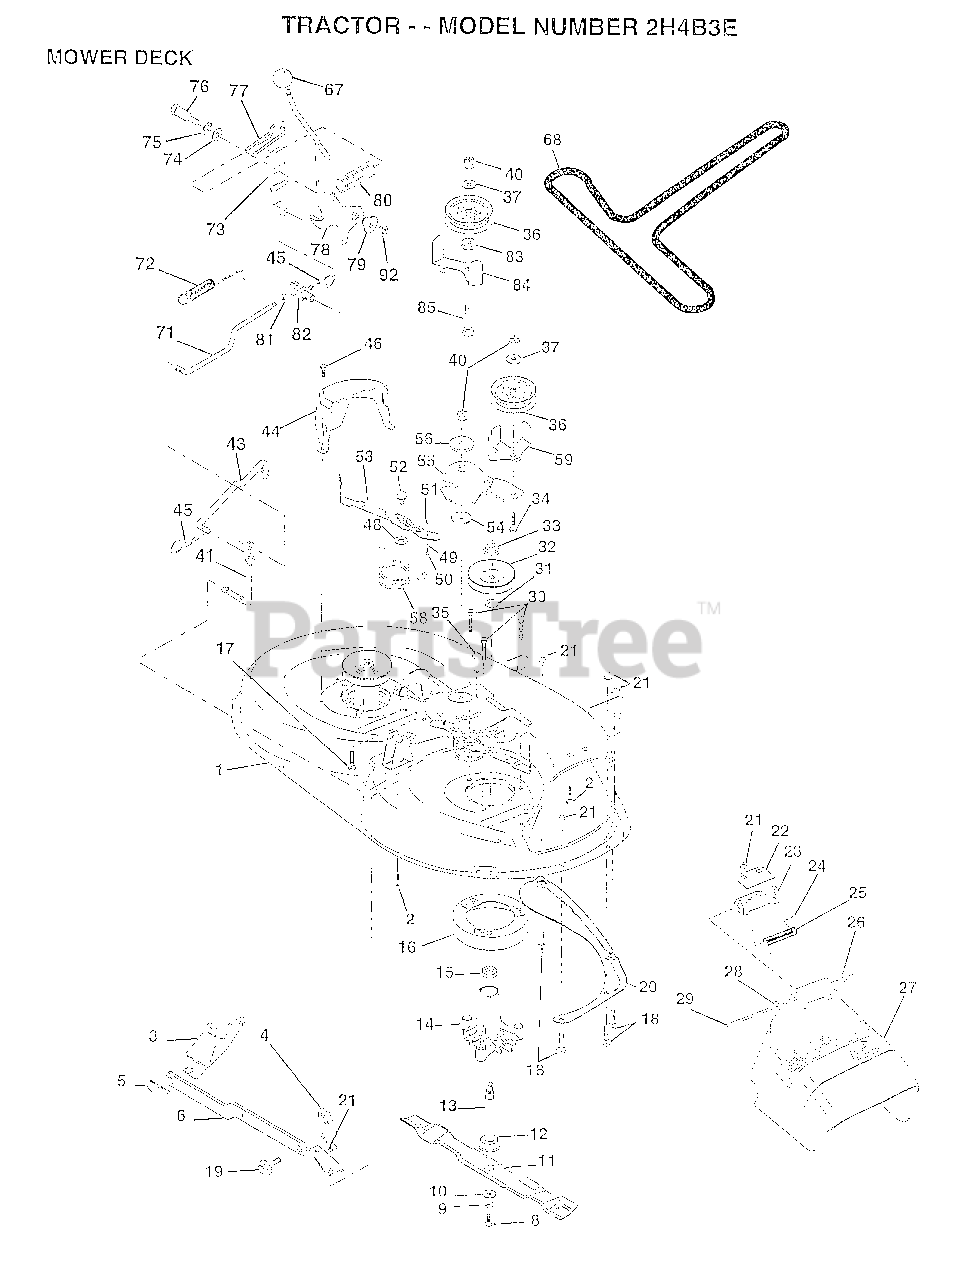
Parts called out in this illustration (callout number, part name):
1	DECK.WELD.42.
2	BOLT
3	BRKT ASM SWAY BAR
4	BRKT DECK SW BAR
8	BLADE BOLT
10	WASHER.HARD.BLADE
11	"BLADE.42"" HIPERF"
12	BEARING.BALL
14	HSG ASM MANDREL
15	BEARING
16	STRIPPER RND MWR
17	BOLT RDHD 3/8-16
18	BOLT
19	BOLT SHD 5/16-18
22	STIFFENER BRKT
23	DEFLECTOR BRKT
25	SPRING TORSION
27	DEFLECTOR.SHIELD
28	WASHER
29	HINGE ROD
31	WASHER
32	PULLEY.MANDREL.42
34	BOLT
35	XMAS TREE FASTNER
36	FLAT IDLER PULLEY
37	WASHER
41	PIVOT ROD
43	ROD CLUTCH W/NIBS
44	GUARD MAND LH BLK
46	SCREW.1/4-20X5/8
48	HARD SMALL WASHER
50	SHOULDER BOLT
51	LOCKNUT
52	BOLT.SHLD.5/16-18
53	BRAKE PAD ARM ASM
54	HARDENED WASHER
56	SPACER RETAINER
58	SPRING TORSN BRAK
59	GUARD IDLER TUV
67	KNOB T(3/8 HOLE)
68	BELT.V.T-PATH
71	ROD CLUTCH 38/42
72	RETURN SPRING
73	CLUTCH ARM SECOND
74	WASHER
75	RING
76	SHOULDER BOLT
77	SPRING KEEPER
79	BUSHING
81	NUT
82	TRUNION ADJ
83	WASHER
85	BOLT RDHD 3/8-16
92	NUT
